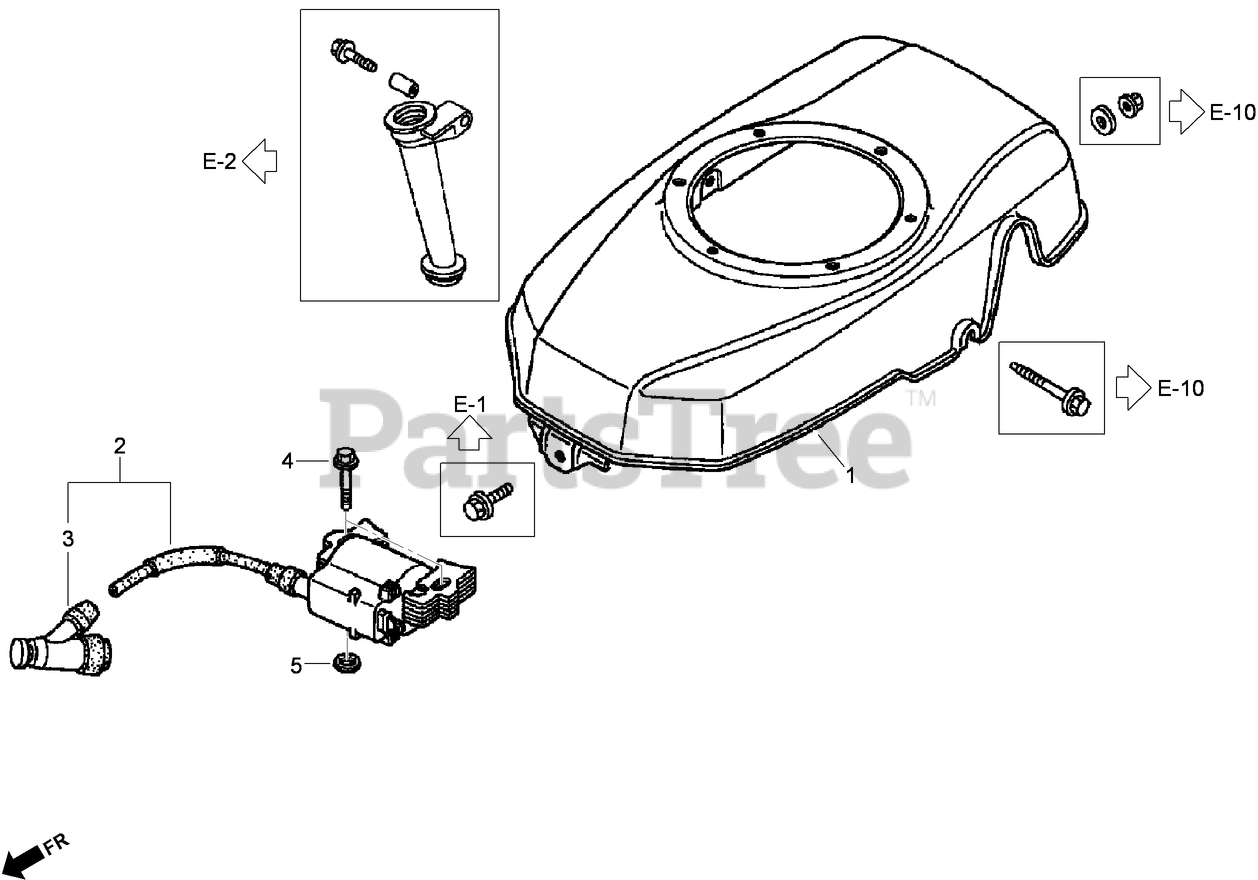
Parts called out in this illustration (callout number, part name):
1	COVER-FAN (N H1) (BLACK)
2	IGNITION COIL ASM
3	NOISE SUPPRESSOR CAP ASM
4	BOLT-FLANGE (6X28) (C T200) (engine serial numbers starting at 6901761)
5	WASHER-PLAIN (6 mm)
